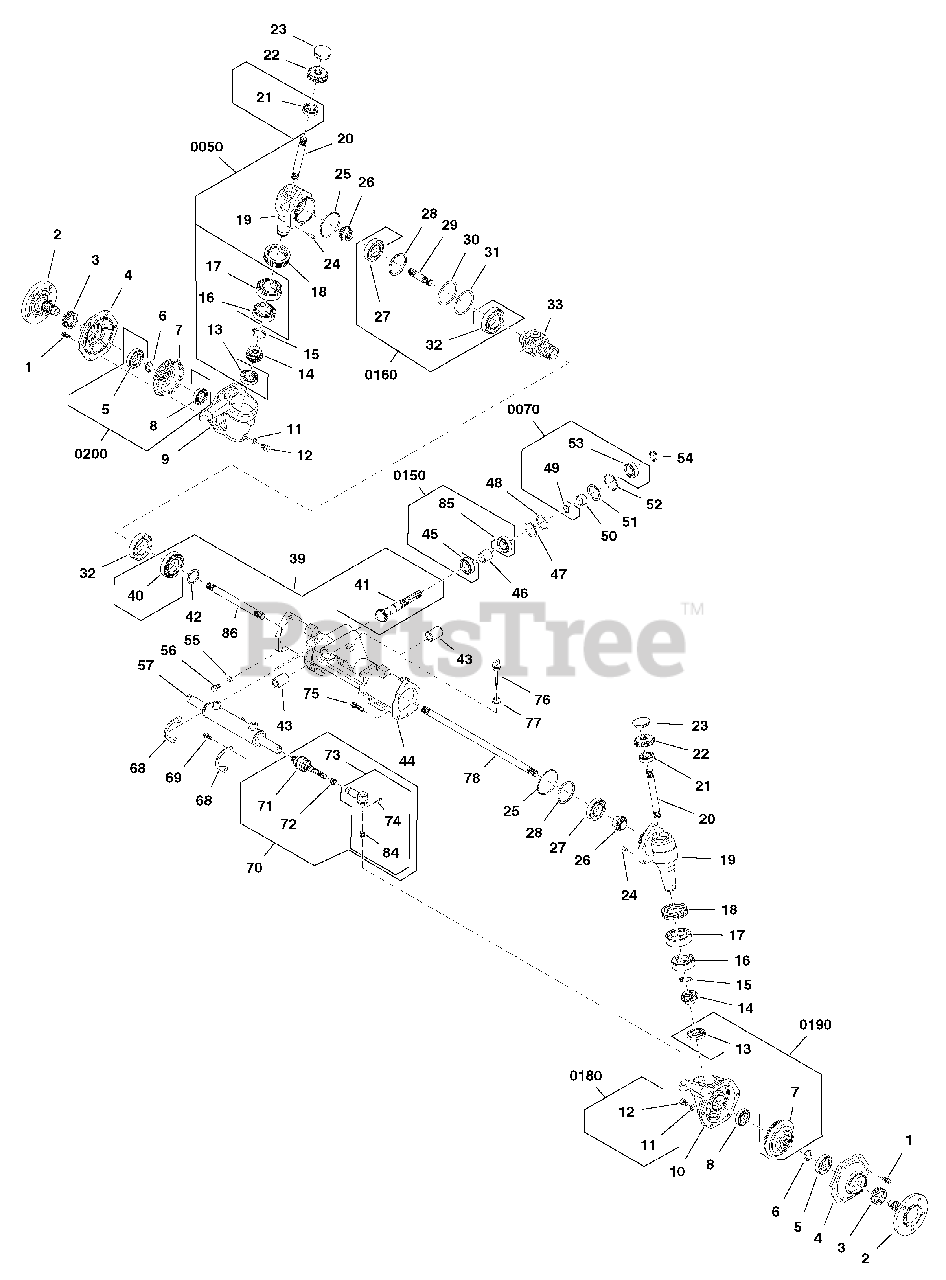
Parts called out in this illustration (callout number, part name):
1	BOLT, Washer
2	AXLE, Front
4	COVER, Front Axle
5	BALL BEARING
6	SNAP RING
7	GEAR, Bevel, 34 Teeth
8	BALL BEARING
8	BEARING BALL
9	CASE, Front Axle, RH
10	CASE, Front Axle, LH
11	WASHER, Seal
12	PLUG
13	BALL BEARING
14	GEAR, Bevel
15	CIR-CLIP, External
16	BALL BEARING
17	BALL BEARING
19	CASE, Bevel Gear
20	ROD, Bevel Gear Shaft
21	BALL BEARING
22	GEAR, Bevel, 19 Teeth
23	COVER, Seal
24	PIN, PARALLEL
26	GEAR, Bevel, 11 Teeth
27	BALL BEARING
28	SNAP RING
29	SHAFT, Differential Gear, RH
32	BALL BEARING
33	FRONT DIFFERENTIAL ASSEMBLY
41	DRIVE PINION
43	BUSH
44	SUPPORT, Front Axle
45	BALL BEARING
46	BUSHING
50	BUSHING
0050	The service part is in development.
51	COLLAR
52	CIR-CLIP
54	CIR-CLIP
55	WASHER, Seal
56	PLUG
57	CYLINDER ASSY
70	BALL JOINT ASSEMBLY
0070	The service part is in development.
71	TIE ROD END
73	BALL JOINT, TIE ROD END
74	SPLIT PIN
75	BOLT
76	GAUGE, OIL
77	SEAL WASHER
78	SHAFT, Differential Gear, LH
85	BALL BEARING
0150	The service part is in development.
0160	The service part is in development.
0180	The service part is in development.
0190	The service part is in development.
0200	The service part is in development.
